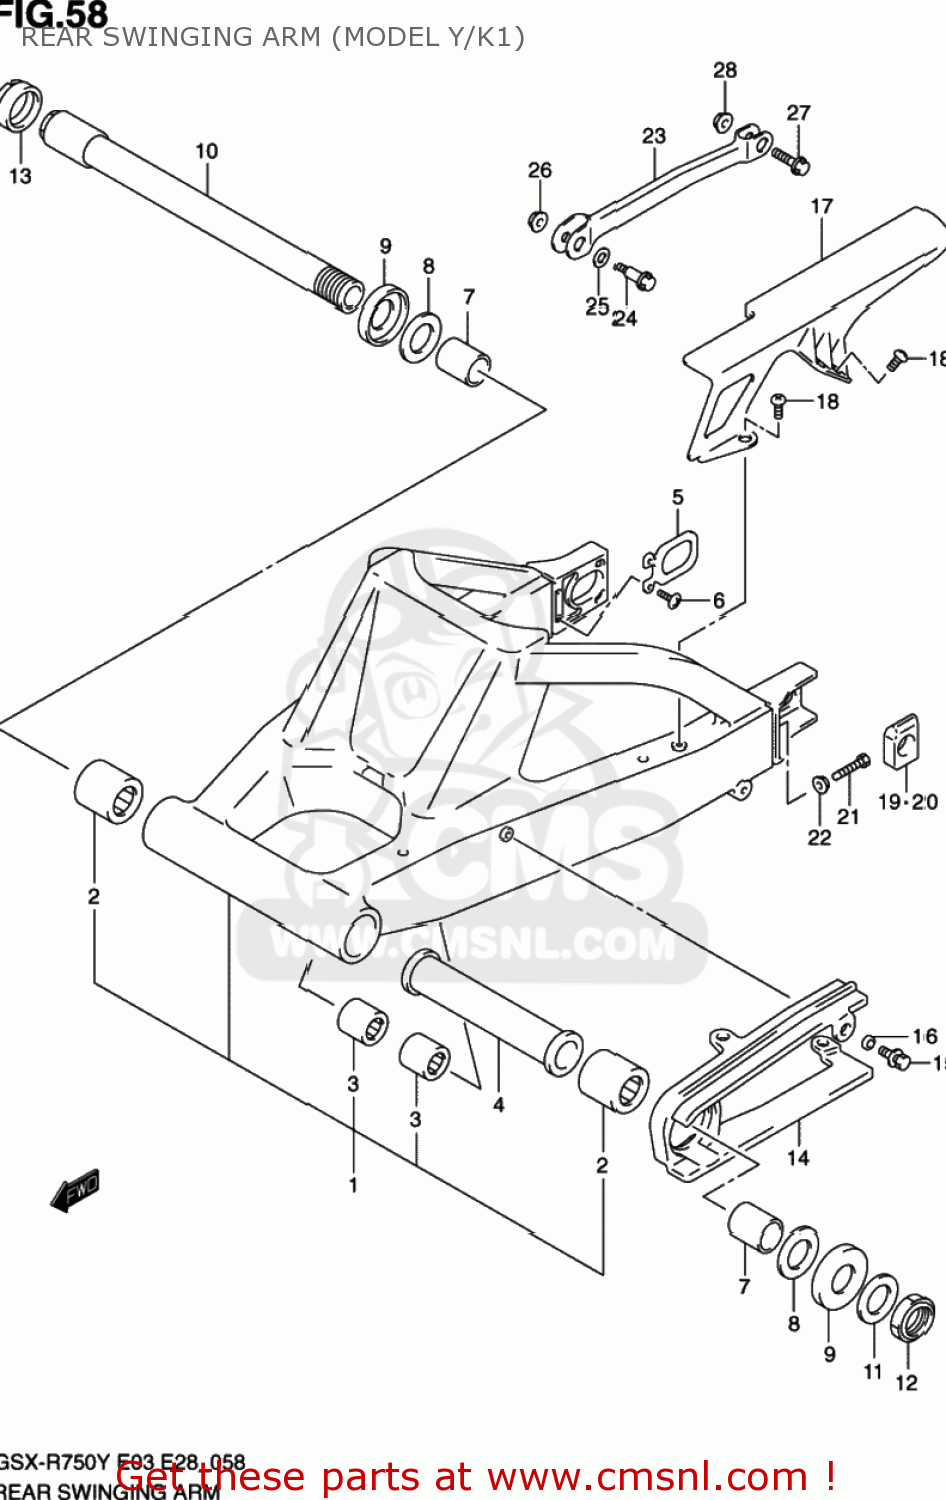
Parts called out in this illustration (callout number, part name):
1	SWINGINGARM ASSY,RR
2	BEARING(30X40X25)
3	BEARING(17X24X20)
4	SPACER,REAR SWING PIVOT,CENTER
5	PLATE,RR SWING ARM BRKT
6	SCREW
7	SPACER,REAR SWING ARM PIVOT
8	WASHER
9	DUST SEAL,RR SWGARM PIVOT
10	SHAFT,RR SWINGINGARM PIVOT
11	WASHER(25.2X42X3.2)
12	NUT
13	NUT,RR SWGARM PIVOT BOLT
14	BUFFER,CHAIN TOUCH DEFENSE
15	BOLT(6X20)
16	SPACER(6.5X9X5)
17	CASE,CHAIN
18	SCREW(6X16)
19	ADJUSTER,CHAIN,RIGHT
20	ADJUSTER,CHAIN,LEFT
21	BOLT(8X50)
22	NUT
23	TORQUELINK,RR
24	BOLT(8X35.5)
25	WASHER(12.5X20X1)
26	NUT
27	BOLT(10X37)
28	NUT
